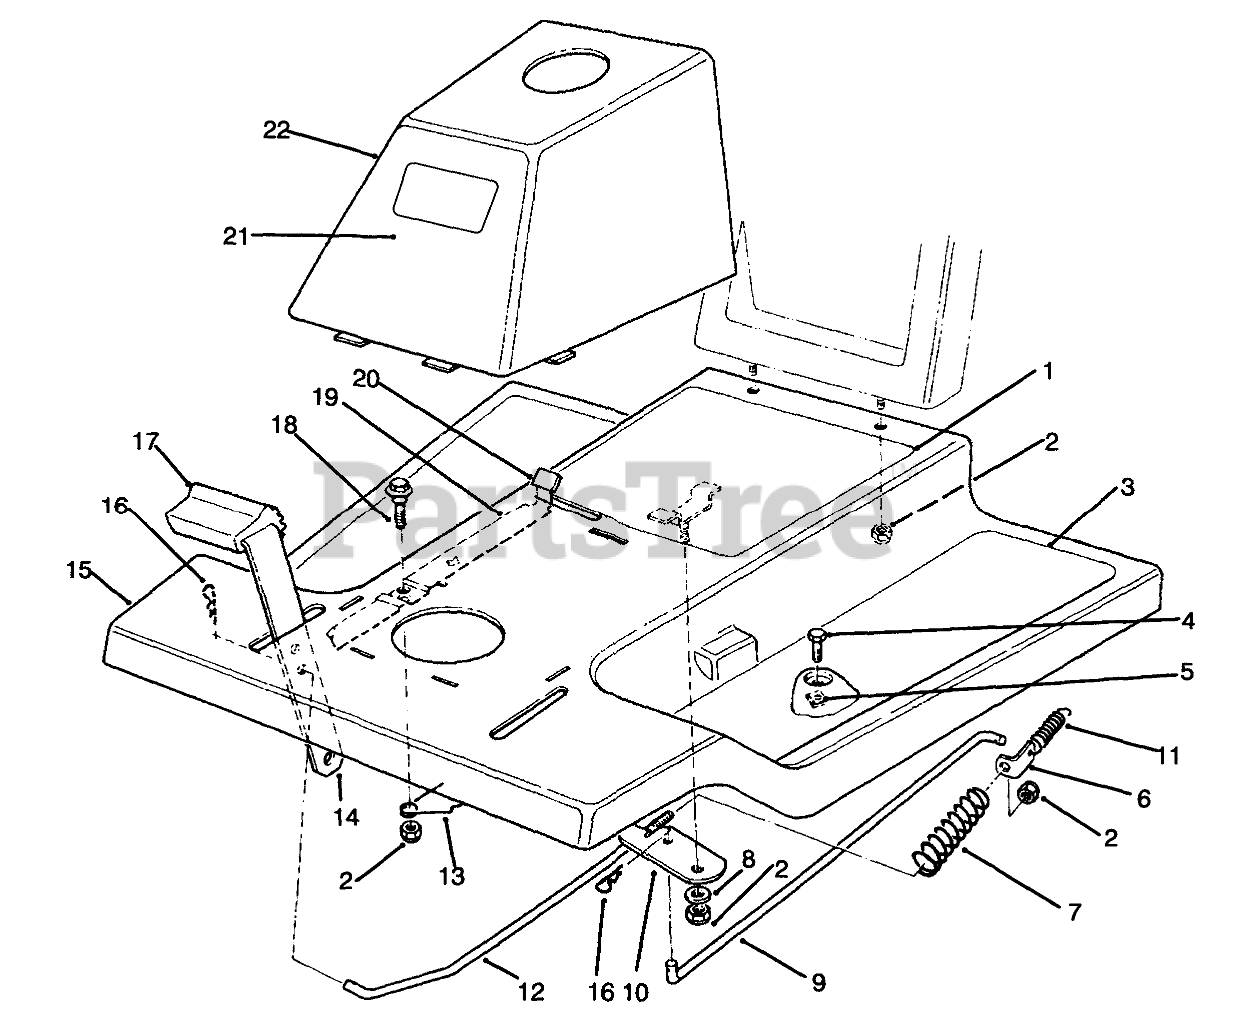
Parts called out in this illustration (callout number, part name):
1	DECAL - INSTRUCTION
2	NUT-LOCK, NI
3	TREAD-FOOT
4	SCREW-HH
5	NUT-TINNERMAN
6	BRACKET-BRAKE RETURN
7	SPRING-TRACTION BRAKE
8	WASHER-PIVOT
9	ROD-TRANS BRAKE
10	LEVER-BRAKE
11	SPRING-IDLER
12	ROD-FRONT BRAKE
13	SPRING-PARKING BRAKE
15	Body W.A.-Front
16	PIN-COTTER
17	PAD-PEDAL
18	SCREW-SHOULDER
19	PARKING BRAKE (BLACK)
20	TIP-PARKING BRAKE
21	DECAL
22	Tower (Incl. Ref.#21)
